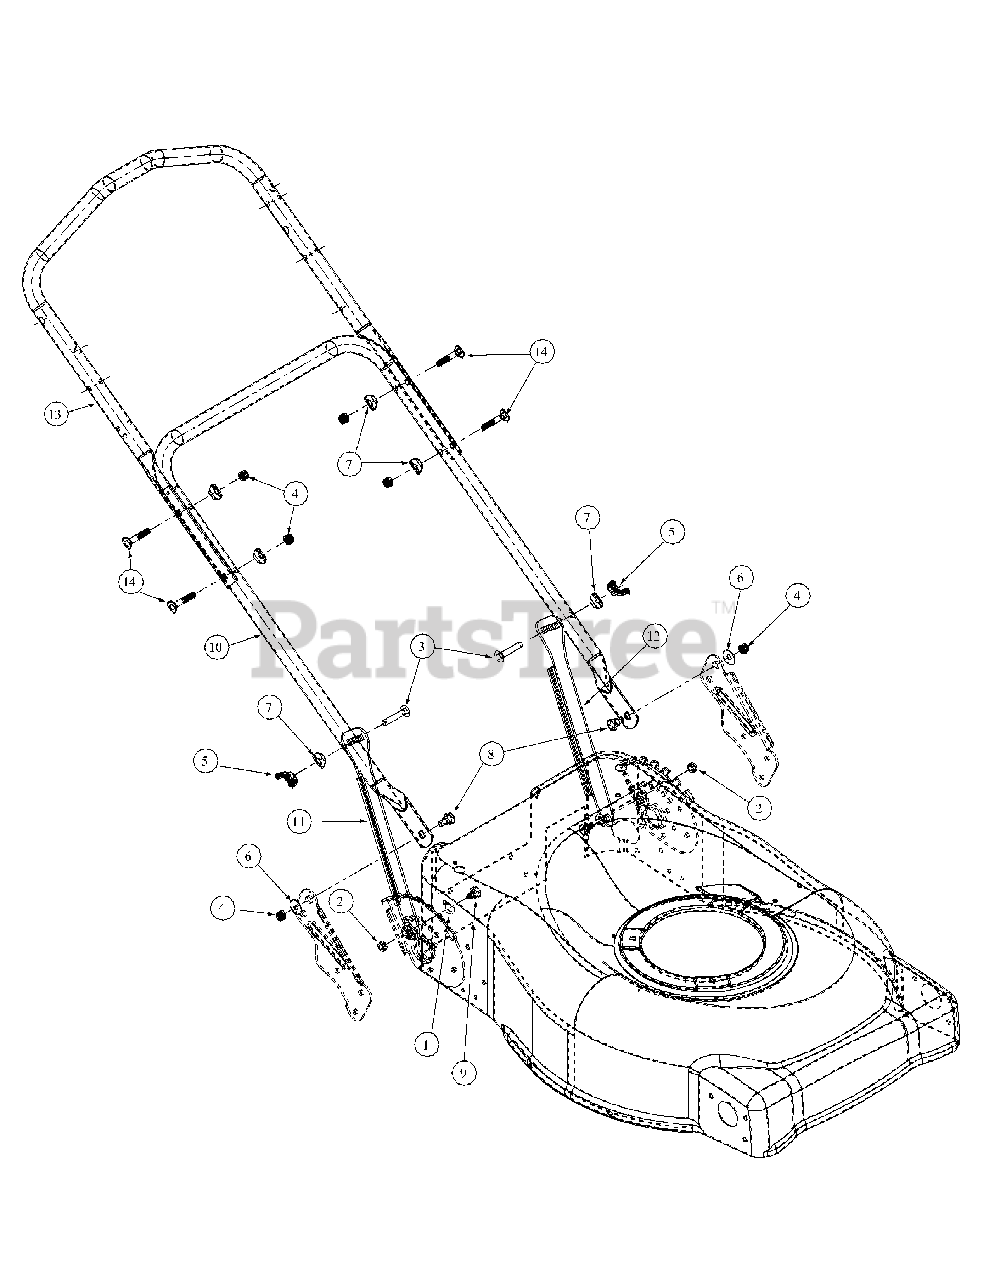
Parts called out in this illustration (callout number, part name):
1	Thrust Washer
2	Lock Nut, 5/16-18,
3	Carriage Bolt, 5/16-18, 1.75
4	Hex Nut, 5/16-18
5	Wing Nut, 5/16-18
6	Belle Washer, .325 x .930 x .045
7	Shoulder Washer, .320 ID x .93 OD
8	Shoulder Screw, .435 x .350, 5/16-18
9	Shoulder Screw, .437 x 1.62 LG
10	Handle, Lower, 1.0"
11	Strut, 3 Position, Right hand
12	Strut, 3 Position, Left hand
13	Upper Handle, 1.0", Self Propelled
14	Carrige Bolt, 5/16-18 X 1.75 Curved
